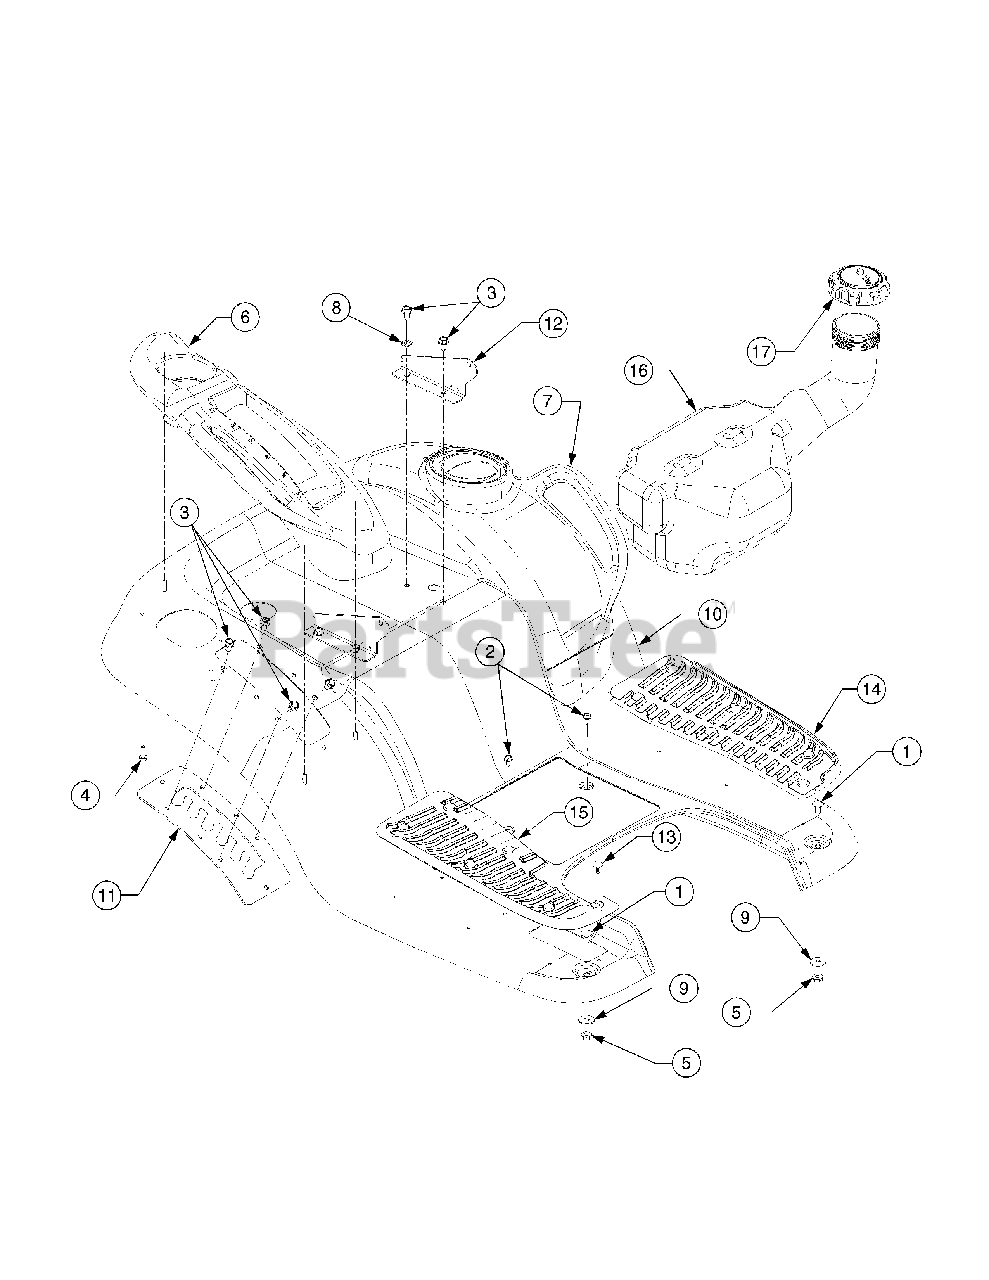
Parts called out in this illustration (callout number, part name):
1	Bolt, Carriage, 5/16-18 x .75 Lg
2	Screw, Hex Wash Hd Tap, 1/4-20 x .5
3	Screw, Hex Wash Hd Tap, 5/16-12, 0.75
4	Screw, 1/4-15, 0.750
5	Nut, Flange Insert Lock, 5/16-18 GRF
6	Cover, Fender, RH
7	Cover, Fender, LH
8	Washer, External Tooth Lock, 5/16
9	Washer, Flat, .349 x 1.00 x .063
13	Clip, Ratchet, .250 Dia
14	Pad, Foot, LH
15	Pad, Foot, RH
16	Tank, Fuel
17	Cap, Fuel
